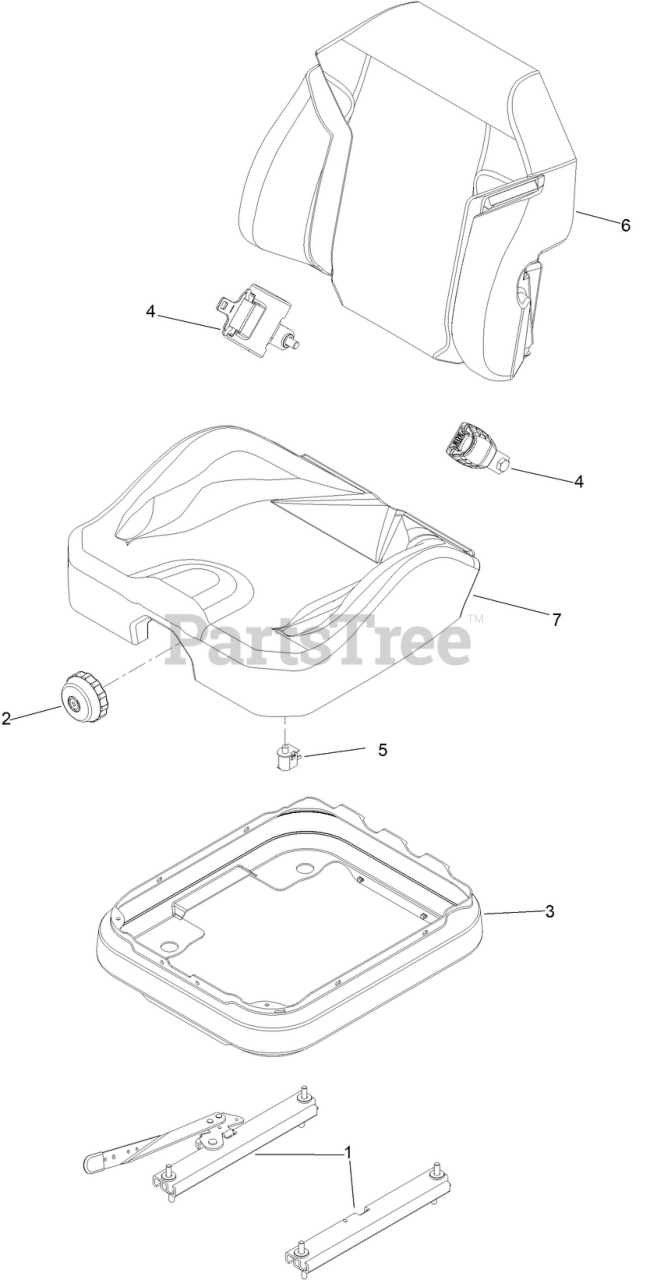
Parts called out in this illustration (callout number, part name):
1	SET, SEAT TRACK
2	KNOB-ADJUSTER
3	BELLOWS-SEAT
4	KIT-SEAT BELT
5	SWITCH-BAIL
6	COVER-BACK, SEAT
7	COVER-BOTTOM, SUSPENSION SEAT
